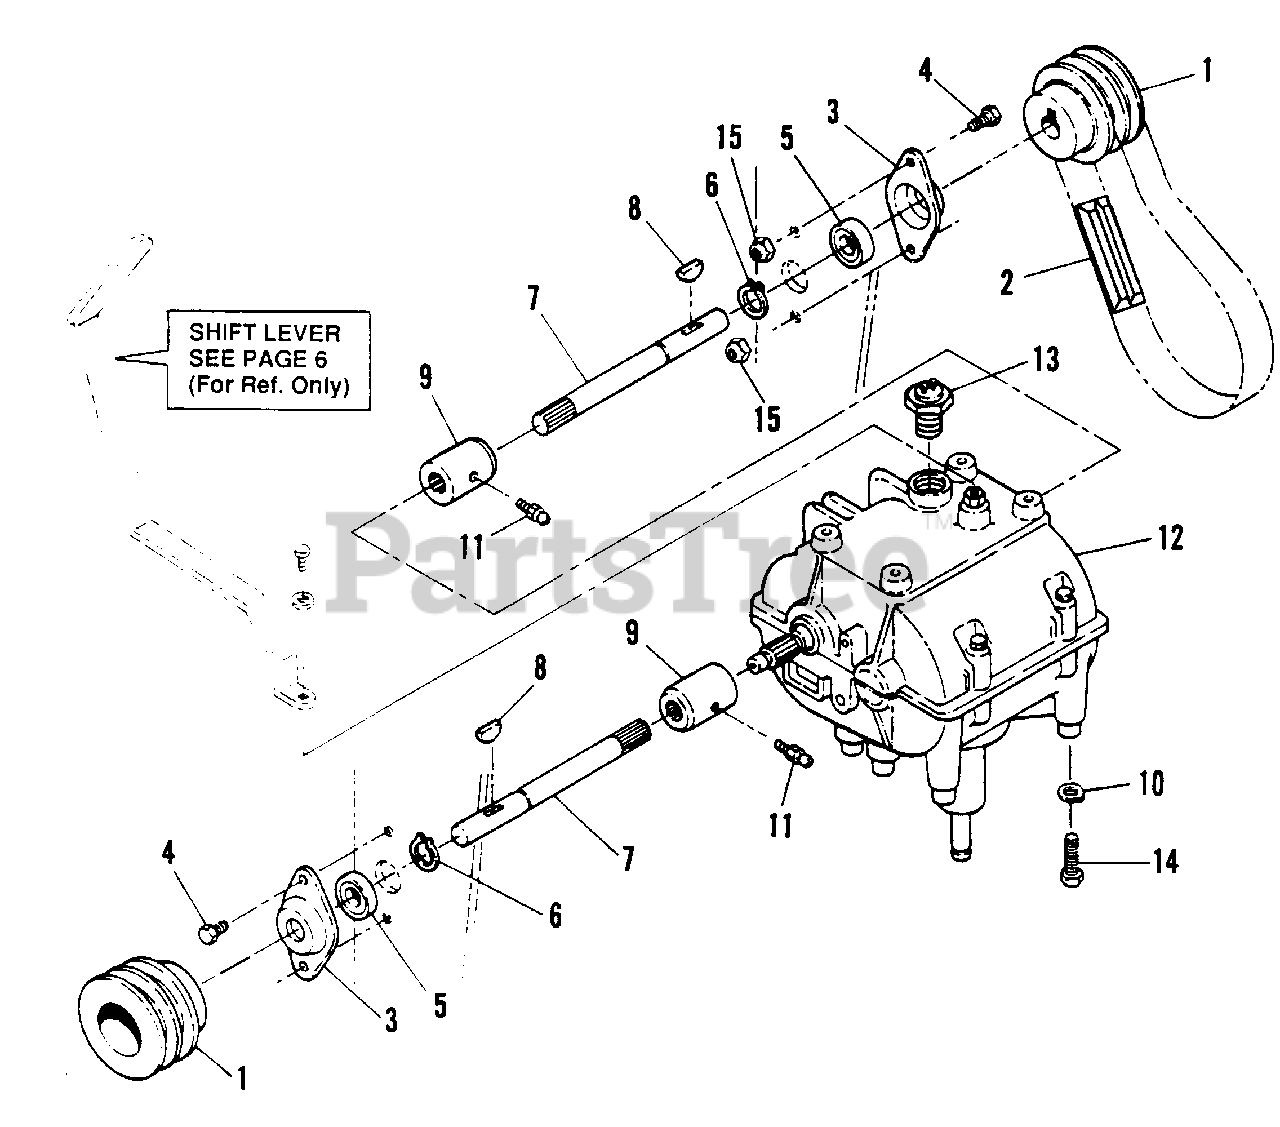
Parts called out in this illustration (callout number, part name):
1	PULLEY, Output
2	BELT, Traction
3	FLANGE, Output, 3/4"
4	SCREW, 1/4" -20 x 3/4" Lg. Hex. Cap
5	BEARING, Output
6	SNAP RING, 5/8"
7	SHAFT, Output
8	KEY, Woodruff #9
9	COUPLER
10	LOCKWASHER, 5/16"
11	GREASE FITTING, 1/4" - 28 Str. Zerk
12	TRANSMISSION
13	SWITCH, Transmission
14	BOLT, 5/16 - 18 x 3/4 Ig.
15	NUT, 1/4" C Nyloc
